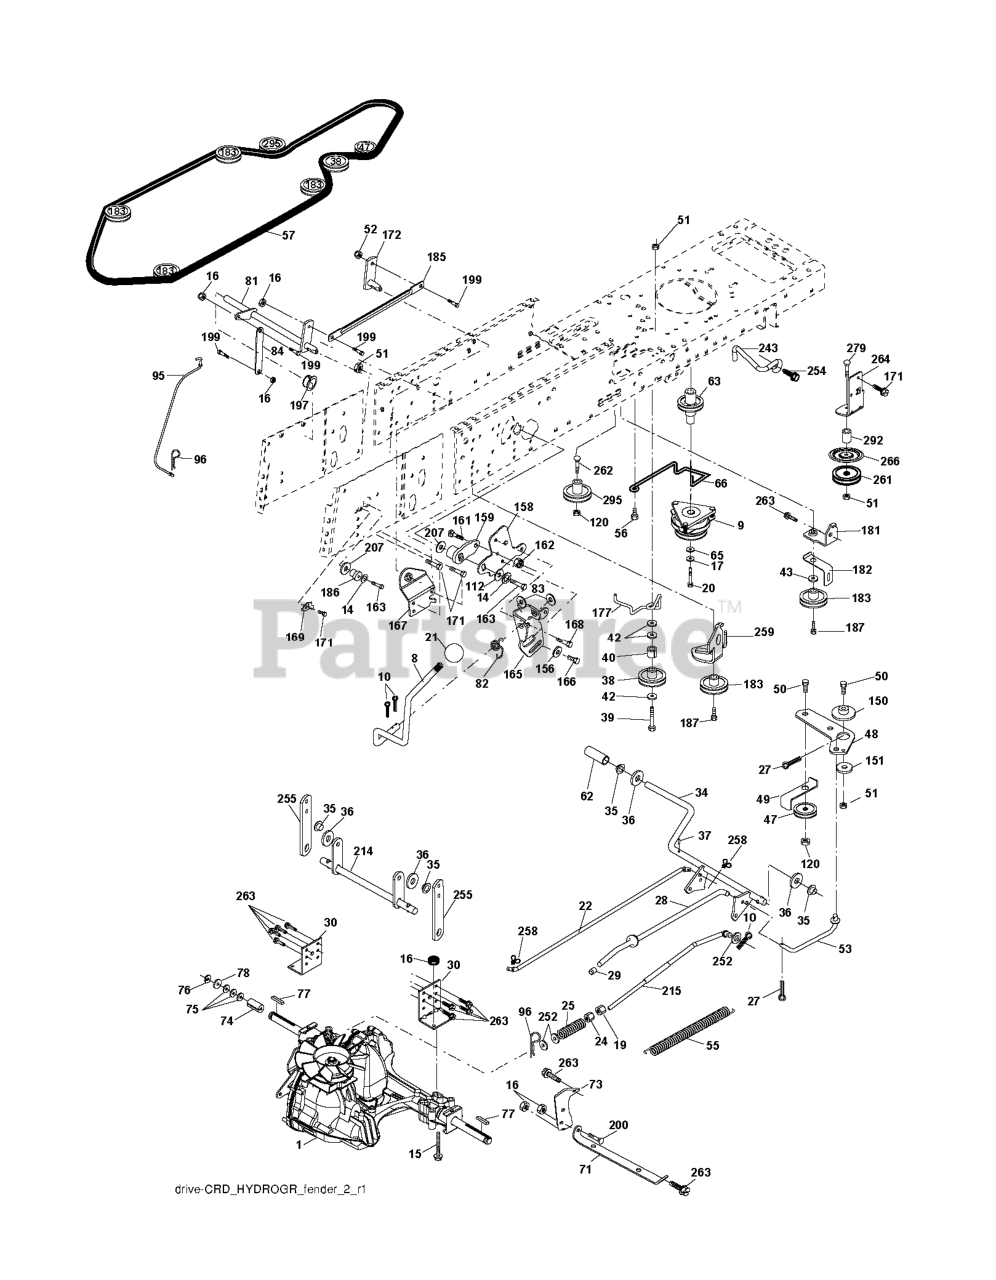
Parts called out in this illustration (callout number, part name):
8	ROD SHIFT FENDER ADJUST LT
9	CLUTCH.ELECTRIC.OGURA.EURO.
10	PIN COTTER
14	LOCKWASHER
15	BOLT HEX 5/16-18 GR 5
16	NUT.71038.31-18.HEX.NYLOCK
17	LOCKWASHER
19	NUT
20	BOLT HEX 7/16-20X4-1/4"
21	KNOB.DUCKHEAD.1/2
22	ROD
24	NUT
25	SPRING BRAKE ROD
27	COTTER PIN
28	ROD, PARKING BRAKE
29	PLUNGER CAP
30	BRKT, TRNSXLE MNT 20"
34	SHAFT, FOOT PEDAL
35	BEARING.NYLON
36	WASHER LT
37	DRIVE PIN
38	PULLEY.FLAT
42	WASHER
43	WASHER T
47	IDLER PULLEY
48	BELLCRANK, CLUTCH
49	RETAIN BELT
50	BOLT.3/8-16X1.50
52	LOCKNUT
53	LINK.CLUTCH.7.66.2005
55	SPRING, RETURN LT
56	SCREW.3/8-16
57	V-BELT 113"
62	PEDAL COVER T
63	PULLEY.ENGINE.CVX.LT
66	KEEPER BELT ENGINE
71	STRAP TORQUE LH HYDRO
73	STRAP TORQUE RH HYDRO
74	SPACER AXLE
77	SQUARE KEY
81	ASM.CROSS.SHAFT.REAR.CRD.0510
82	SHIFT SPRING
83	WASHER
84	LINK.PNT.TRANSAXLE.0510.CRD
95	LINK
96	RETAINER M
112	WASHER LT
120	NUT LOCK FLG 3/8-16 UNC
150	BUSHING.BELLCRANK.GRD.DR
151	WASHER 12/32X2X10GA
156	WASHER.SRRTD.5/16
158	BRACKET
159	RB HUB.SHIFT
161	BOLT
162	NUT.CROWNLOCK.1/4
163	BOLT
165	RP BRACKET
166	CAPSCREW.HXHD.FLG.5/16-18X.625
167	BRACKET.SUPT.SHIFT.CRD
168	BOLT.SHOULDER.5/16-18X
169	PLATE.FASTENING.CROSS.SHAFT
171	SCREW LT
172	LINK
181	BRACKET
182	BELT GUIDE
183	PULLEY.V-IDLER.GRND.DR
185	LINK
186	HUB.TAPERED.ROUND.CRD
187	BOLT.5/16-18X1.25
197	NYLINER SNAP 5/8" ID
199	BOLT SHOULDER 5/16-18 UNC
200	BOLT
207	WASHER NYL
214	LEVER
215	ROD
243	BRACKET, ANTI-ROTATION
252	WASHER
254	SCREW 3/8-16X1
255	SHAFT
258	CLIP RETAINER
259	BRACKET
261	FLAT IDLER PULLEY
263	SCREW, 3/8-16X3/4
266	PROTECTOR
279	BOLT
292	SPACER
295	PULLEY IDLER COMPOSITE
